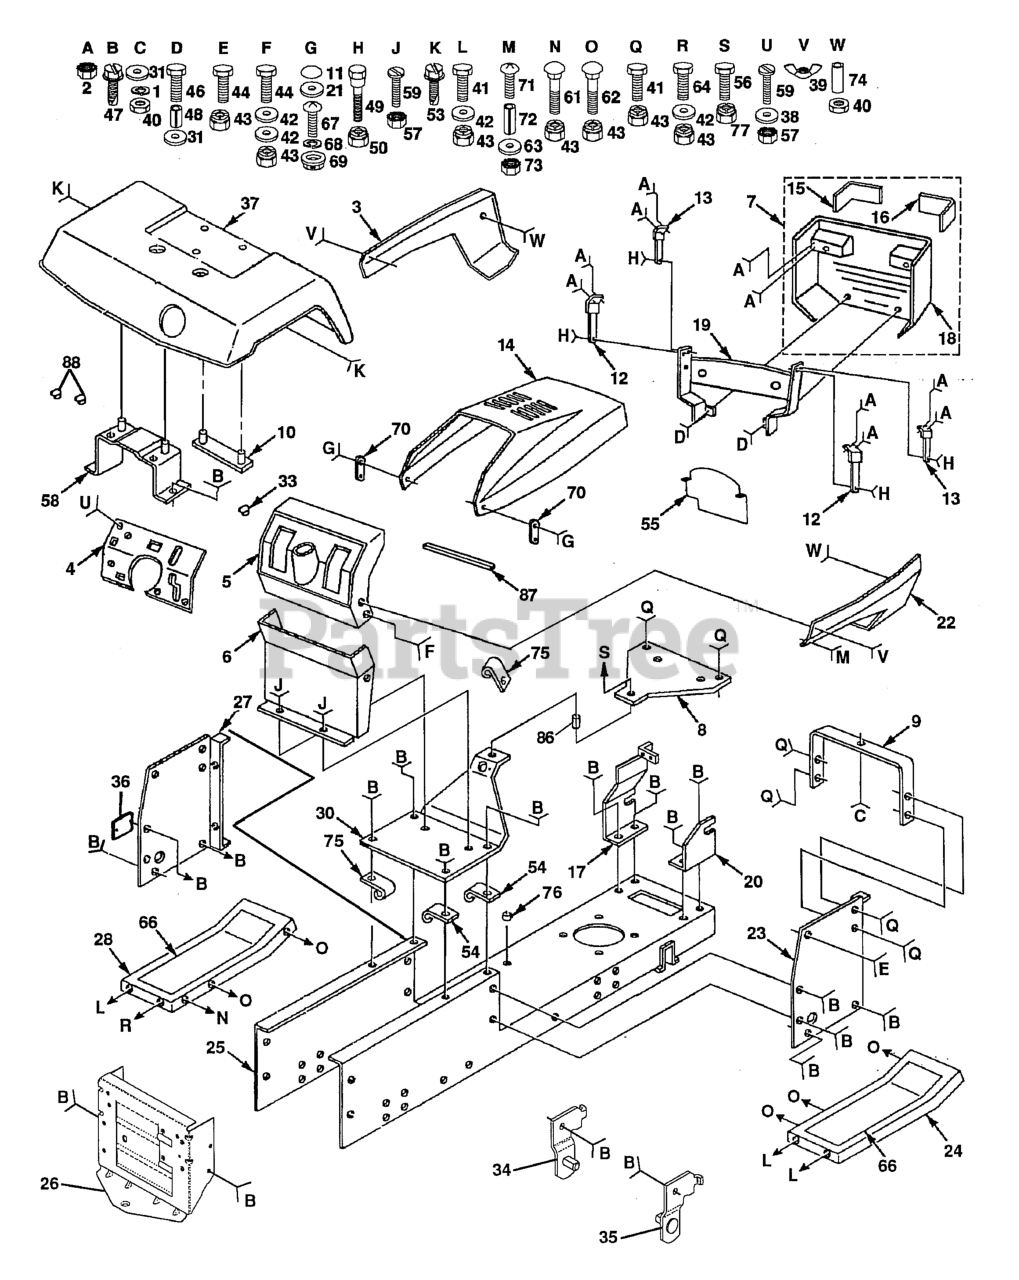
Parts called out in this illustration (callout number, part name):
1	LOCKWASHER
2	NUT
3	SIDE PANEL ASSY LH
4	DASH PLATE
6	DASH LOWER YT NLA
7	GRILL COMPLETE
8	PLATE, BATTERY
9	SUPPORT ASS'Y
10	STRAP
11	SNAP CAP LT
12	STRAP ASSY LT
13	STRAP ASSY LT
14	HOOD
15	LENS LH
16	LENS RH
17	SUPPORT RH YTH
18	GRILL
19	SUPPORT ASS'Y
20	SUPPORT LH YTH
22	SIDE PANEL ASSY RH
23	PANEL DASH RH
24	PAD,SPACER
25	CHASSIS
26	STRETCH DRAWBAR
27	PANEL DASH LH
28	ROLL PIN NLA
31	WASHER PM
33	PLUG-DASH T
34	BRACKET LH PIVOT
35	BRACKET RH PIVOT
36	COVER ACCESS
37	FENDER
38	WASHER
39	WING NUT
40	NUT
42	WASHER
44	BOLT
47	SCREW
49	BOLT T
50	NUT.CROWNLOCK.1/4
53	SCREW LT
54	CLIP,INSULATOR
55	BAFFLE,REAR UPPER
56	Bolt, Hex, Fin. 5/16-18 UNC x 2
57	NUT
58	FENDER BRKT
59	Screw, Machine 5/16-18 UNC x 3/4
61	BOLT D
62	BOLT
64	BOLT
66	PAD FOOTREST T
67	SCREW
68	LOCKWASHER #10
69	WELDNUT
70	LATCH.HOOD.
71	RP SCREW
73	NUT **
74	SPACER NLA
75	CLIP T
76	SNAP BUSHING T
77	NUT.71038.31-18.HEX.NYLOCK
87	FOAM-STRIP LT
88	NUT-PUSH YT
